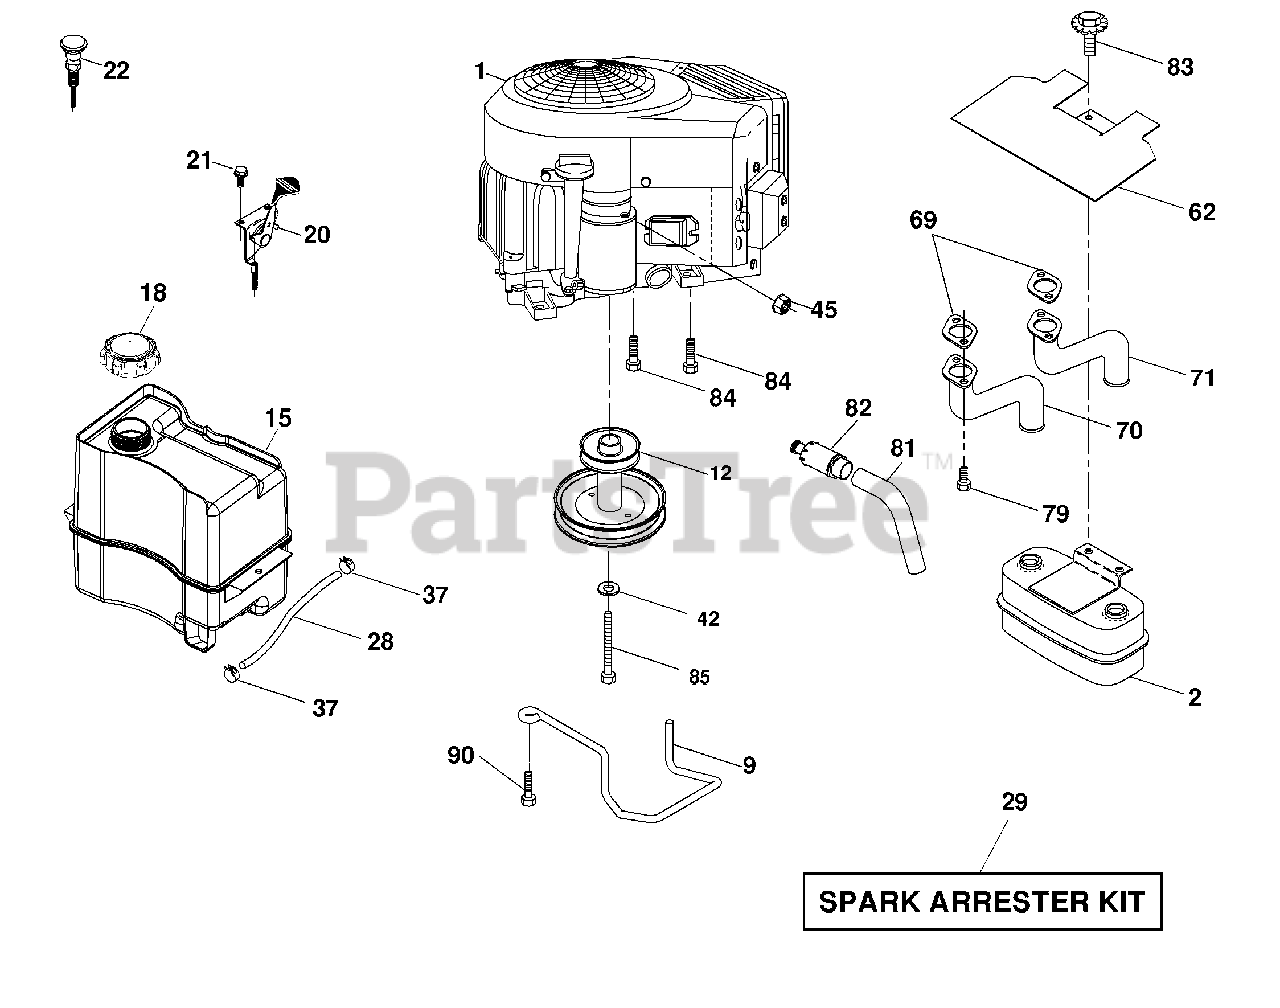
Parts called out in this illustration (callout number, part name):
9	Keeper Belt Engine
12	Pulley Engine
15	Tank Fuel
18	Cap Asm
20	Control Throttle
21	Screw 10 x 3/4 Single Lead Hex
22	Control Choke
28	Fuel Line
29	Spark Arrester Kit
37	Clamp Hose
42	Washer Lock 7/16
45	Nut Keps Hex 1/4-20 unc
62	Shield Heat Muffler
70	Exhaust Tube LH
71	Exhaust Tube RH
79	Screw Socket Head
81	Tube Drain Oil Easy
82	Plug Drain Oil
83	Bolt 5/16-18 UNC x 3/4 w/Sems
84	Screw 3/8-16 x 1-1/4
85	Bolt Hex 7/16-20 x 4 x Gr. 5-1.5 Thr
90	Screw 3/8-16 x 1
